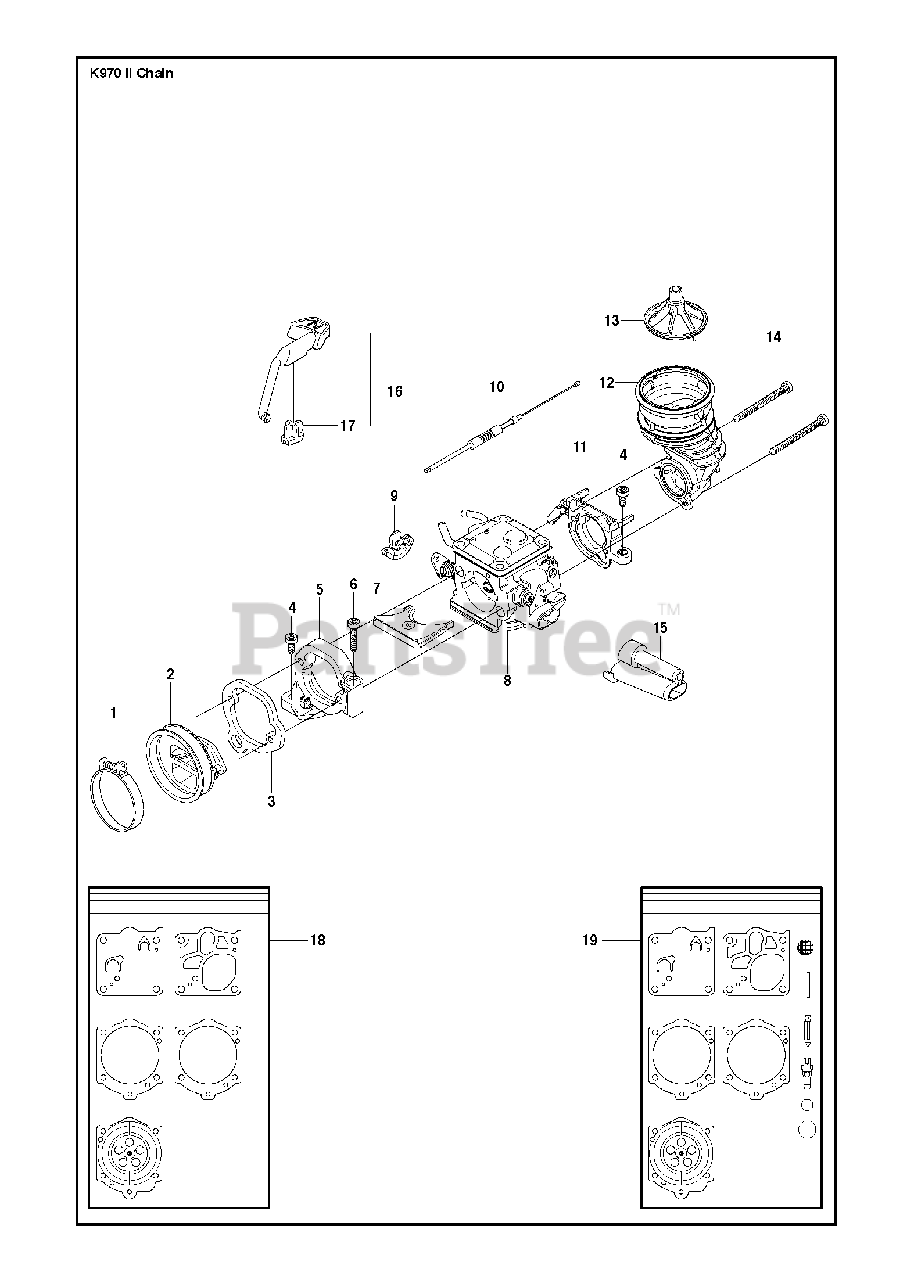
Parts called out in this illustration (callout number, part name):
1	HOSE CLAMP
4	SCREW ITXSCM
6	SCREW ITXSCM
8	CARBURETTORRWJ-7
10	THROTTLE CABLE ASSY
11	FLANGE INLET PIPE
14	SCREW ITXSCM
15	CHISEL GUIDE
16	CHOKEIncl. 17
17	WEAR PROTECTION
18	GASKET KITWalbro RWJ-5
19	REPAIR KITWalbro RWJ-5
